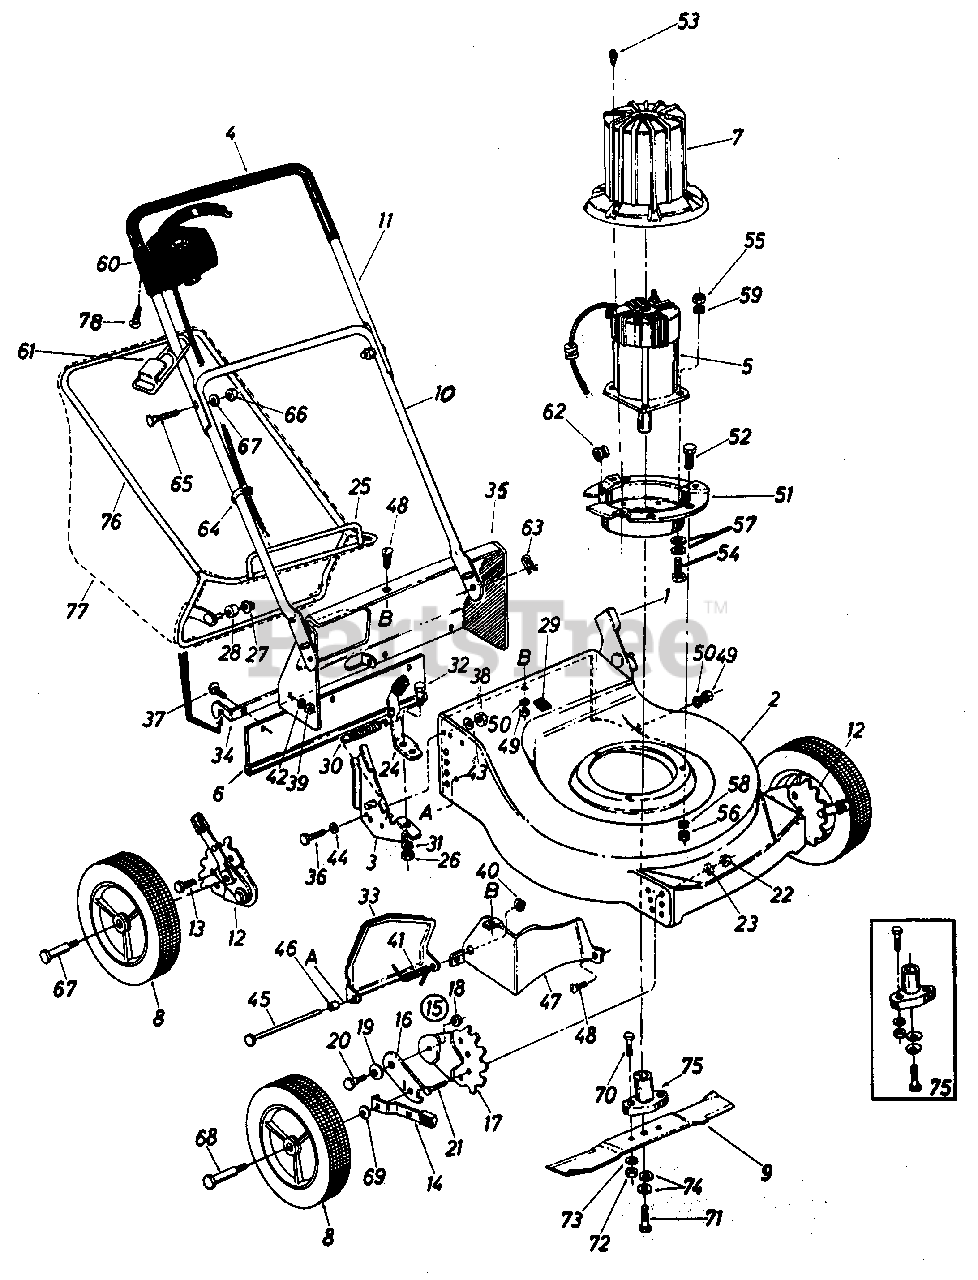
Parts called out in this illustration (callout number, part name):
1	Handle Brkt. Ass'y.-L.H.
2	20" Deck Ass'y.
3	Handle Brkt. Ass'y.-R.H.
6	Rear Flap Ass'y.
8	Plastic Wheel 8 x 1.75
9	20" Blade
10	Lower Handle (Chrome)
11	Upper Handle (Chrome)
12	Height Adjust. Ass'y.-L.H.
13	Hex Bolt 3/8-16 x .75" Lg.*
14	Spring Lever Ass'y. w/Knob
15	Height Adjust. Ass'y.-R.H.
16	Pivot Bar
17	Index Plate
18	Hex Cent. L-Nut 3/8-16 Thd.
19	Bell-Wash. .515" I.D. x 1.14" O.D.
20	Shld. Bolt .500" Dia. x .295"
21	Hex Bolt 3/8-16 x .75" Lg.*
22	Hex Nut 3/8-16 Thd.*
23	L-Wash. 3/8" I.D.*
24	Grass Catcher Lock Lever w/Knob
27	Push Nut 3/8" Rod
28	Plastic Roller
30	Extension Spring
31	L-Wash. 5/16" I.D.*
32	Shld. Bolt .437" Dia. x .162"
33	Chute Door
34	Grass Catcher Hitch Brkt.
35	Rear Deck Section
36	Hex Bolt 1/4-28 x .75" Lg.*
37	Carr. Bolt 1/4-20 x .75" Lg.*
38	Hex Nut 1/4-28 Thd.*
39	Sems Nuts 1/4-20 Thd.*
40	Push Nut 1/4" Rod
41	Torsion Spring
42	Fl-Wash. .285" I.D. x 1.25 O.D.
43	Bell-Wash. 1/4" I.D. x .88" O.D.
44	L-Wash. 1/4" I.D.*
45	Hinge Pin
46	Spacer
47	Rear Baffle
48	Carr. Bolt 1/4-20 x .50" Lg.*
49	Hex Nut 1/4-20 Thd.*
50	L-Wash. 1/4" I.D.*
51	Adapter Plate
52	Hex Bolt 3/8-16 x 1.00" Lg.*
53	Hex Wash. Hd. F-Tap Scr. #10-32 x .314" Lg.
54	Hex Bolt 1/4-20 x 1.00" Lg.*
55	Hex Nut 1/4-20 Thd.*
56	Hex Nut 3/8-16 Thd.*
57	Fl-Wash. 3/8-1.D. x 1.0" O.D.
58	L-Wash. 3/8" I.D.*
59	L-Wash. 1/4" I.D.*
60	Control w/Cord
61	Restraint
62	Cord Restraint
63	Inter. Cot-Pin 5/16" Dia.
64	Cable Tie
65	Curve Carr. Bolt 5/16-18 x 1.38" Lg.*
66	Hex Nut 5/16-18 Thd.*
67	L-Wash. 5/16" I.D.
68	Bell-Wash. .400" I.D. x .88" O.D.
69	Shld. Bolt .498" Dia. x 1.450"
70	Hex Bolt 5/16-24 x 1.00" Lg.*
71	Hex Bolt 5/16-24 x .75" Lg.*
72	Hex Nut 5/16-24 Thd.*
73	L-Wash. 5/16" I.D.*
74	Bell-Wash. .345" I.D. x .88 O.D.*
75	Blade Adapter Kit
76	Grass Catcher Upper Frame
77	Grass Bag
78	Truss Mach. AB-Tap Scr.
